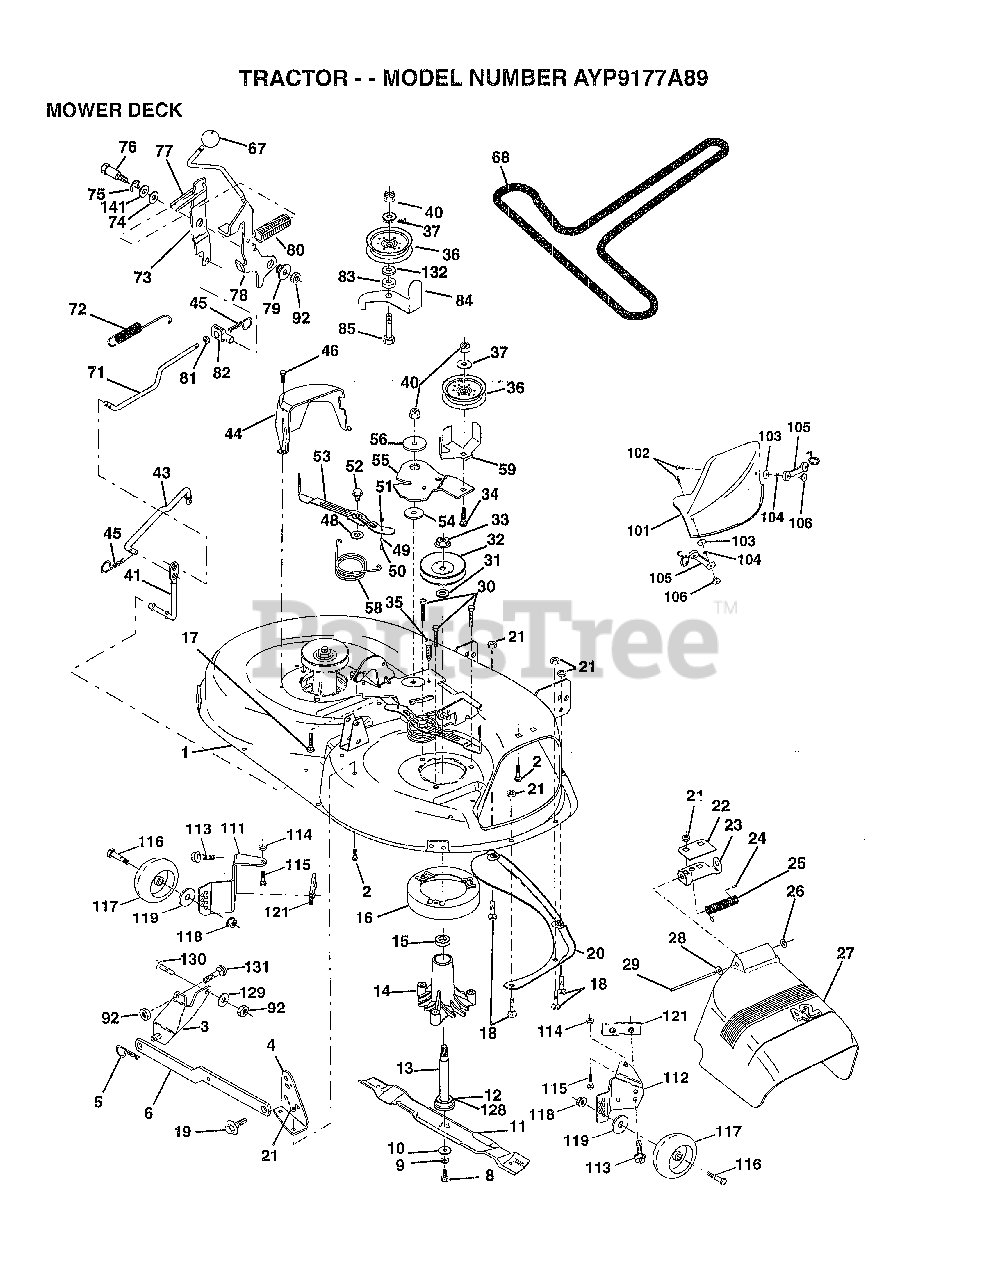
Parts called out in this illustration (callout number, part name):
1	DECK.WELD.42.
2	BOLT
3	BRKT ASM SWAY BAR
4	BRKT DECK SW BAR
8	BLADE BOLT
10	WASHER.HARD.BLADE
11	"BLADE.42"" MULCHER"
12	BEARING.BALL
14	HSG ASM MANDREL
15	BEARING
16	STRIPPER RND MWR
17	BOLT RDHD 3/8-16
18	BOLT
19	BOLT SHD 5/16-18
20	BAFFLE VORTEX 42
22	STIFFENER BRKT
23	DEFLECTOR BRKT
25	SPRING TORSION
27	DEFLECTOR.SHIELD
28	WASHER
29	HINGE ROD
30	"SCREW-THD ROLL,WA"
31	WASHER
32	PULLEY.MANDREL.42
34	BOLT
35	XMAS TREE FASTNER
36	FLAT IDLER PULLEY
37	WASHER
41	PIVOT ROD
43	ROD CLUTCH W/NIBS
44	GUARD MAND LH BLK
46	SCREW.1/4-20X5/8
48	HARD SMALL WASHER
49	ROLLER ASM-CAM
50	SHOULDER BOLT
51	LOCKNUT
52	BOLT.SHLD.5/16-18
54	HARDENED WASHER
55	ARM-IDLER
56	SPACER RETAINER
58	SPRING TORSN BRAK
59	GUARD IDLER TUV
67	KNOB.RD.7/16-14
68	BELT.V.T-PATH
71	ROD CLUTCH 38/42
72	RETURN SPRING
73	CLUTCH ARM SECOND
74	WASHER
75	RING
76	SHOULDER BOLT
77	SPRING KEEPER
78	LEVER.ASM.CLUTCH
79	BUSHING
80	SPRING.CLUTCH.MWR
81	NUT
82	TRUNION ADJ
83	WASHER
84	"KEEPER-BELT,FIXED"
85	BOLT RDHD 3/8-16
92	NUT
101	"COVER.MULCH.42"""
102	SCREW
103	WASHER #10
104	LOCKWASHER
105	LATCH ASSY.BAGGER
106	WELDNUT
111	BRACKET.GWHL.LH.
112	BRACKET.GWHL.RH.
113	SCREW
116	BOLT.SHOULDER
117	WHEEL GAGE DONUT
118	LOCKNUT
119	WASHER
121	BRACKET.EXTRD.GWL
128	WASHER.FELT.
129	WASHER
130	BOLT
132	WASHER GT
141	WASHER .T
